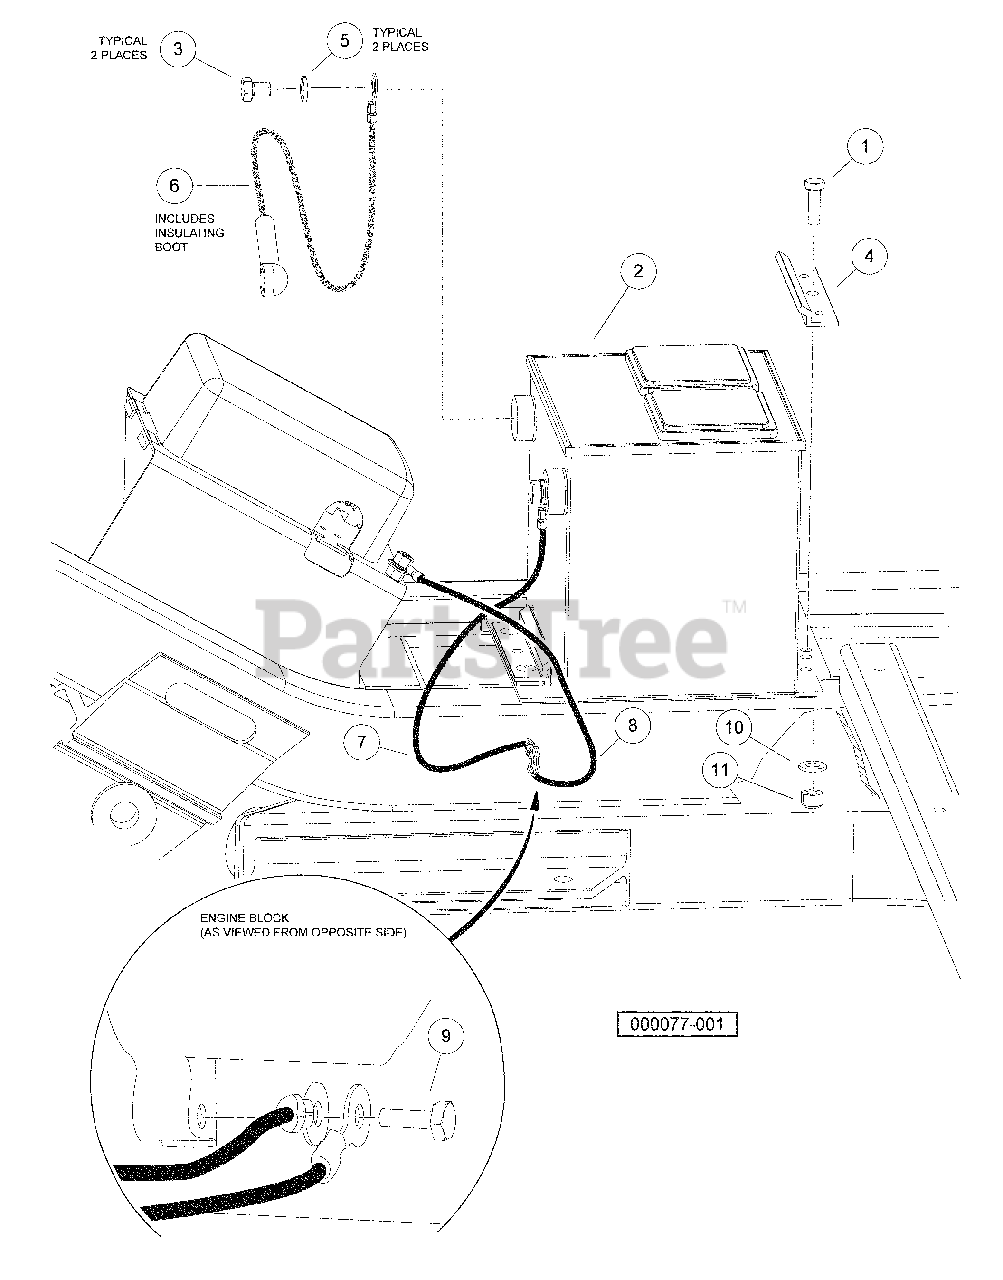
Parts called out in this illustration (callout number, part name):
1	Screw, 5/16-18 X 1.00 Hex Cap
2	Battery, 12-Volt
3	Screw, 3/8-16 X 0.50 Stainless Steel Hex-Head
4	Clamp, Battery
5	Lockwasher, 3/8 Stainless Stl
6	Asm, #6 Red Wire
7	Asm, #6 Blk Wire
8	Asm, #6 Blk Wire
9	Bolt, M6 X 1 X 16 Loctite
10	Washer, 5/16 Type A Flat
11	Locknut, 5/16-18 Nylon Insert
